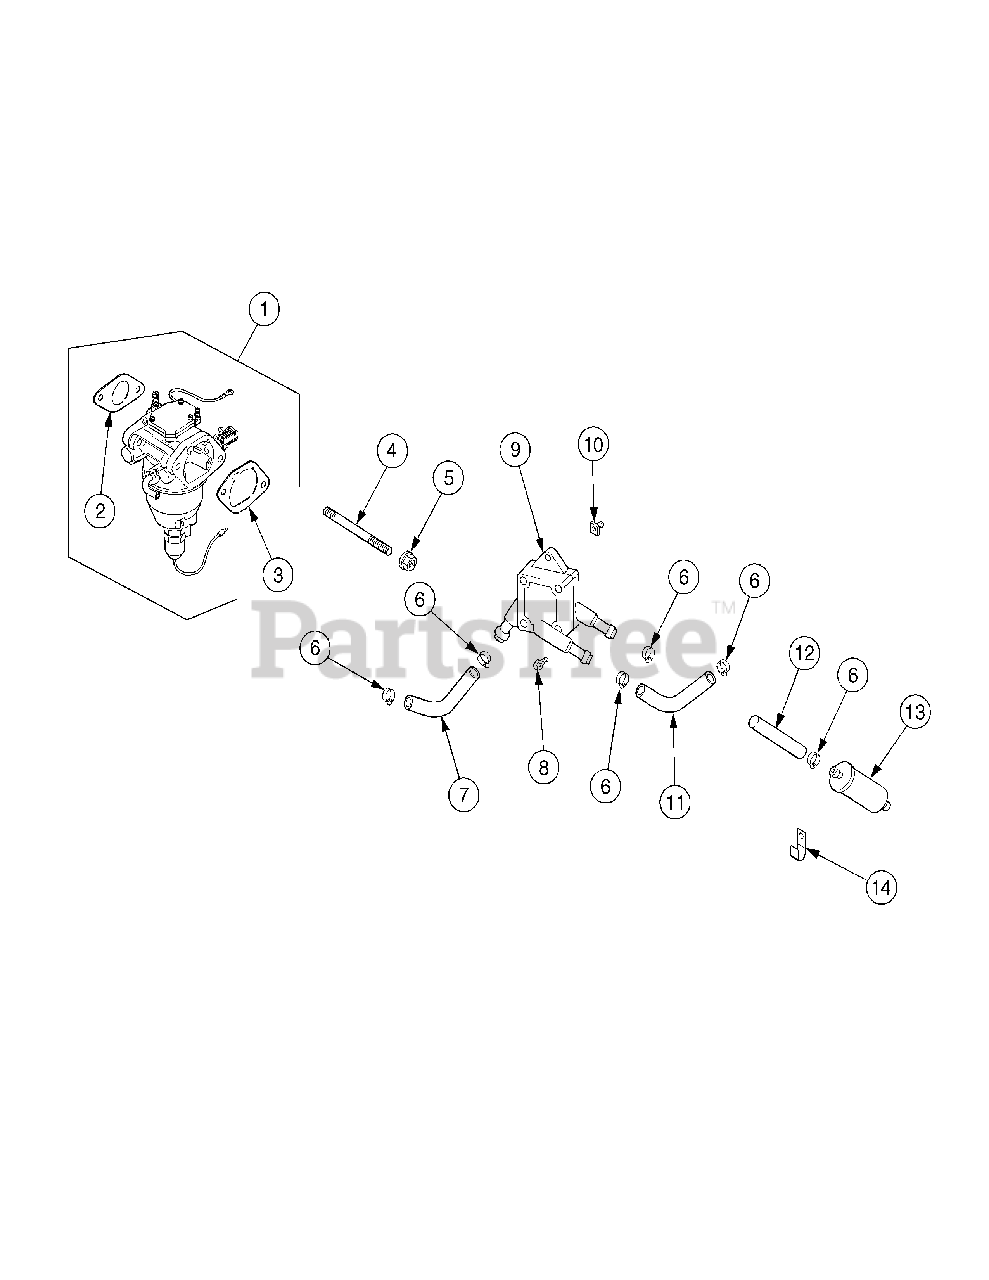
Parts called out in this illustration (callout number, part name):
1	Kit, Carburetor w/Gaskets
2	Gasket, Carburetor
3	Gasket, Air Cleaner Base
4	Stud, Intake Manifold
5	Nut, Hex Flange, M6-1.0
6	Clamp, Hose
7	Line, Fuel, 11"
8	Screw, Hex Cap, M6-1.7 x 18
9	Pump, Pulse Fuel
10	Nut, Plastic
11	Line, Fuel, 11-1/2
12	Line, Fuel, 13-3/4
13	Filter, Fuel
